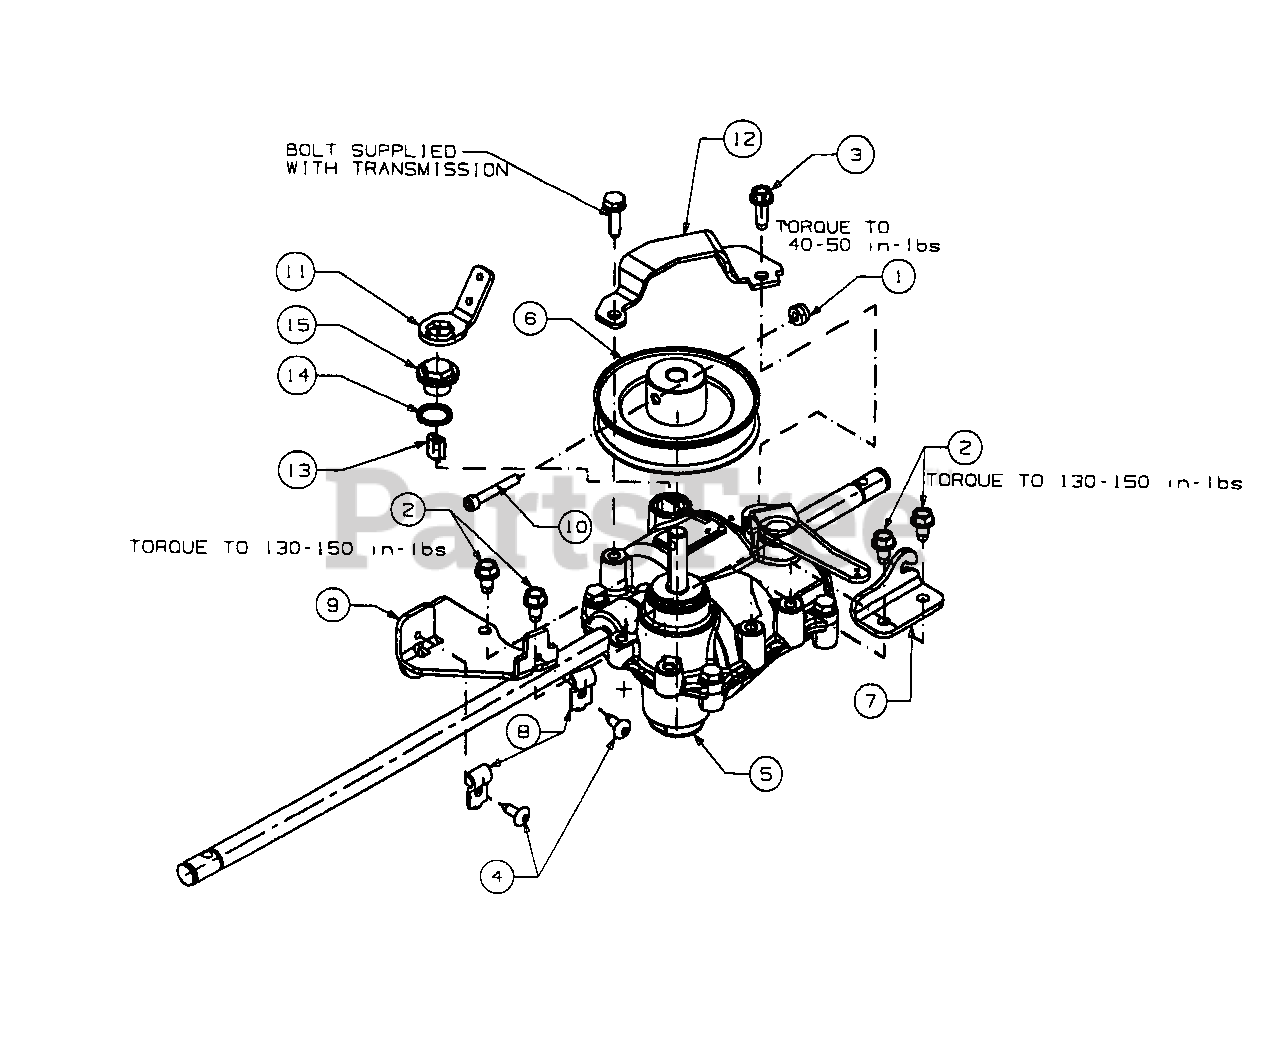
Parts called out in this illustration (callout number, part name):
1	NUT:NYL:LOCK #10-24
2	SCR:TT:1/4-20: .500:HX INDWSH
3	SCR:TT:1/4-20:0.750:HX INDWSH
4	SCR:8:#10-16:0.500: TRUSTRX1
5	TRANS ASM: 3-SPEED: WBM
6	PULLEY:TRANS:3/8 V X 3.50 OD
7	BRKT:SPG;TRANS, TUFF TORQ
8	CLAMP:CBL: 3/16
9	BRKT:CLUTCH:TRANS, TUFF TORQ
10	SCR:SOC:10-24 X 1.25
11	BRKT: SHIFT
12	BRKT: SHIFT: RET.
13	SHIM: S/P 21"
14	SEAL:O-RING:3-SPEED WBM
15	CAP:CLUTCH:3-SPEED WBM
